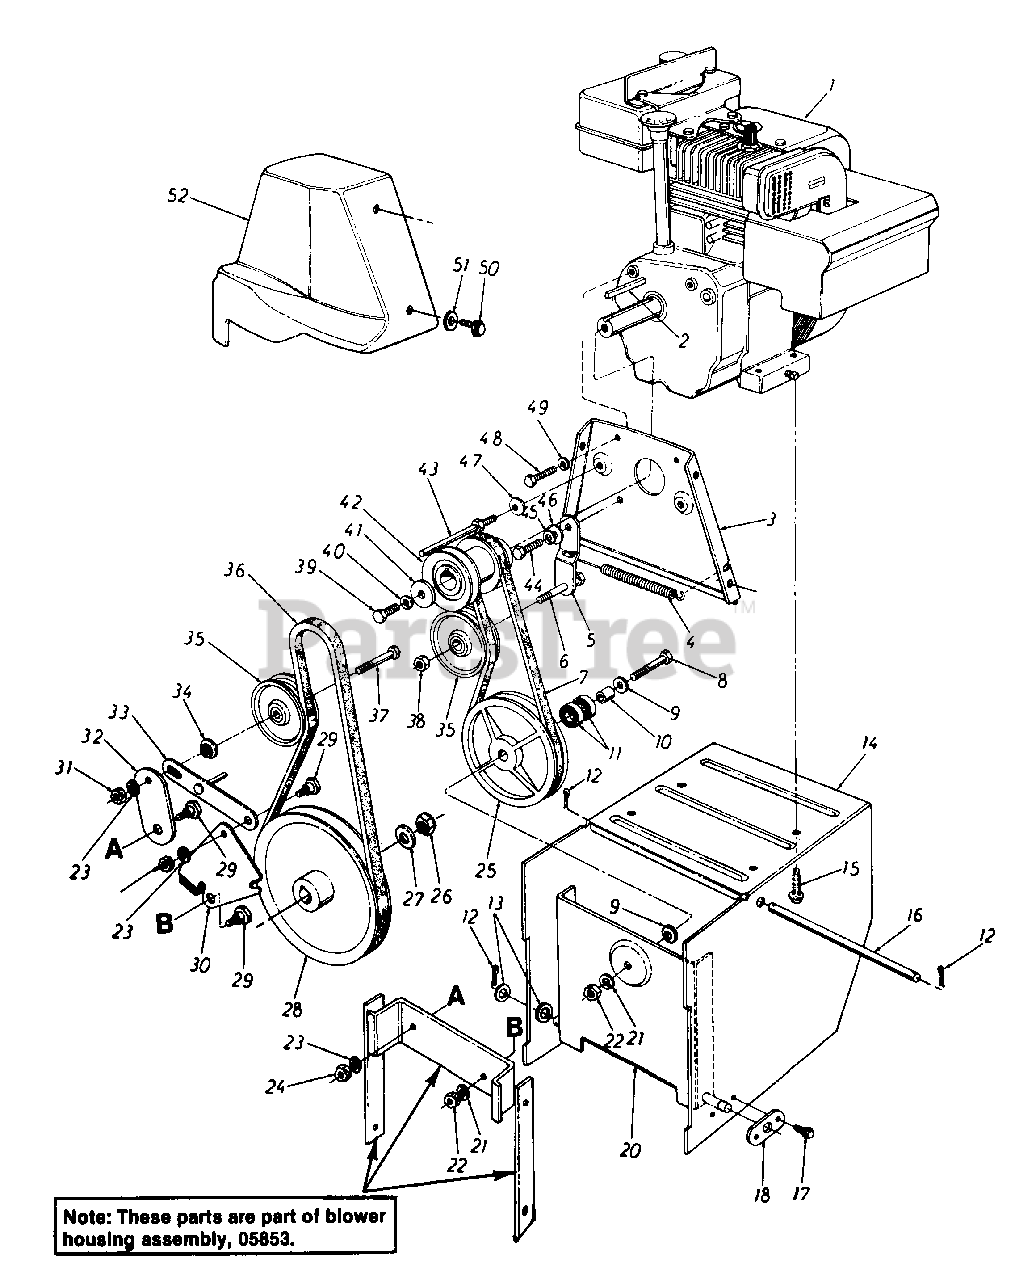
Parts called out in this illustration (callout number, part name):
1	Engine - 5 H.P.
2	Sq. Key 3/16" x 3/16" x 1.50" Lg.
3	Engine Plate Ass'y.
4	Extension Spring .38" O.D. x 3.25" Lg.
5	Drive Clutch Idler Brkt.
6	Hex Bolt 3/8-24 x 1.25" Lg.
7	"V"-Belt 3/8" x 29.0" Lg.
8	Hex Bolt 3/8-24 x 1.50" Lg.
9	Fl-Wash. .38" I.D. x .88" O.D. x .06
10	Spacer .38" I.D. x .62" O.D. x .75" Lg.
11	Ball Bearing
12	Cotter Pin 3/32" Dia. x .75" Lg.
13	Fl-Wash. .53" I.D. x 1.00" O.D. x .06
14	Frame Ass'y.
15	Hex Wash. Hd. Self-Tap Scr. 3/8-16 x 1.25" Lg.
16	Shaft .50" Dia. x 9.50" Lg.
17	Hex Wash. Hd. Self-Tap Scr 1/4-20 x .50" Lg.
18	Axle Bracket
20	Drive Pulley Support Brkt. Ass'y.
21	L-Wash. 3/8" I.D.
22	Hex Ins. Jam L-Nut 3/8-24 Thd.
23	L-Wash. 3/8" I.D.
24	Hex Ins. L-Nut 3/8-16 Thd.
25	6.00" O.D. Drive Pulley Ass'y.
26	Hex Jam Cent. L-Nut 5/8-18 Thd.
27	Fl-Wash. .64" I.D. x .94" O.D. x .06
28	1/2" V-Pulley .625" I.D. x 7.50" O.D.
29	Shld. Bolt .625" Dia. x .170" Lg. (3/8-16)
30	Brake Bracket Ass'y
31	Hex Ins. L-Nut 3/8-16 Thd.
32	Auger Clutch Idler Brkt.
33	Brake Linkage Ass'y.
34	Shld. Spacer .625" I.D.
35	Flat Idler 2.25" O.D.
36	"V"-Belt 3/8" x 38.0" Lg.
37	Hex Bolt 3/8-16 x 1.75" Lg.
38	Hex Ins. Jam L-Nut 3/8-24 Thd.
39	Hex Bolt 5/16-24 x 1.50" Lg.
40	L-Wash 5/16" I.D.
41	Fl-Wash .40" I.D. x 1.25" O.D. x .157
42	Double Groove Engine Pulley
43	Stud 3/8-16 x 3.62" Lg.
44	Hex Bolt 5/16-24 x 1.00" Lg.
45	L-Wash 5/16" I.D.
46	Shld. Spacer .320" I.D.
47	Bell-Wash. .40" I.D. x .88" x .06
48	Hex Bolt 5/16-24 x .62" Lg.
49	L-Wash 5/16" I.D
50	Hex Wash. Hd. Self-Tap Scr. 1/4-20 x .50" Lg.
51	Fl-Wash. .28" I.D. x .75" O.D. x .06
52	Belt Cover
